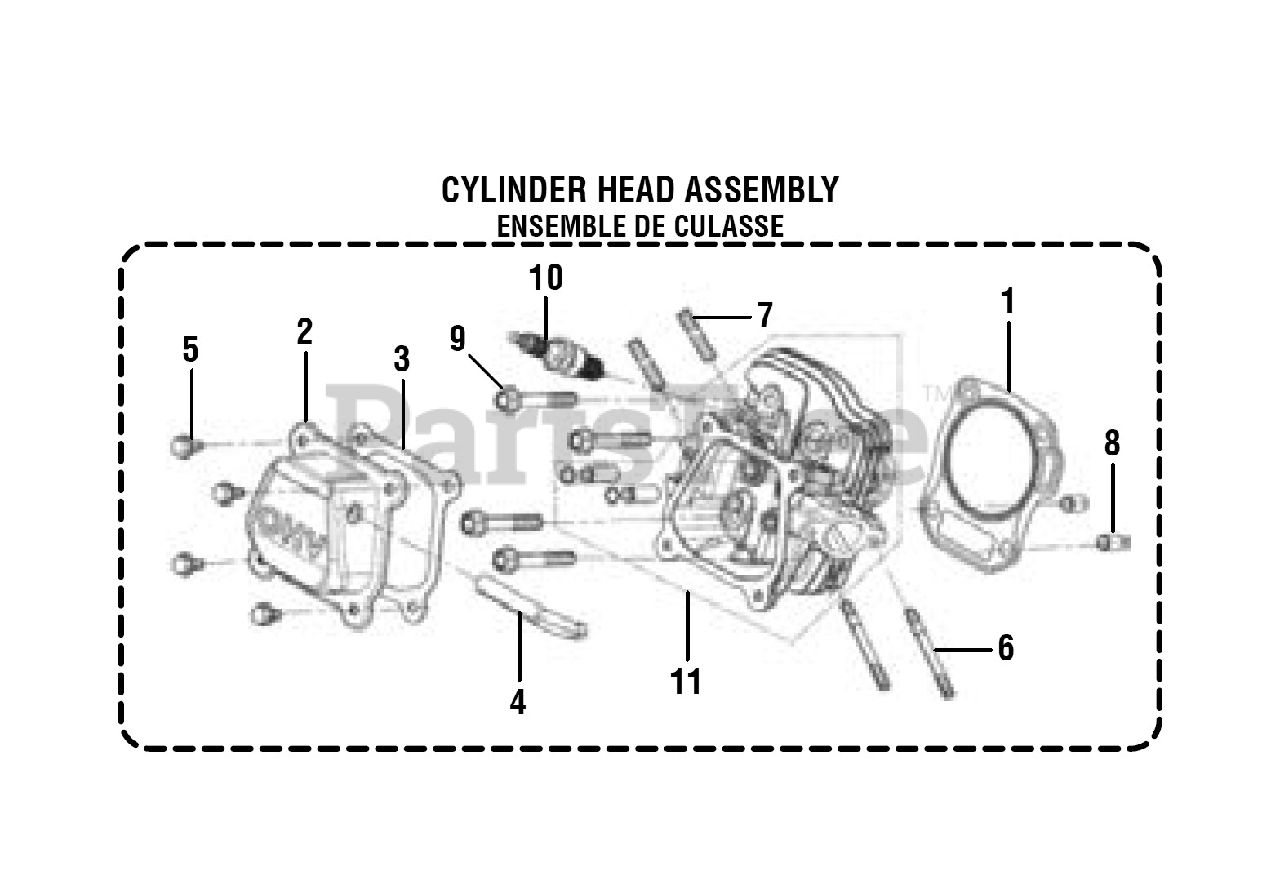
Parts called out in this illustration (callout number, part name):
1	Cylinder Head Gasket
2	Cylinder Head Cover Assembly
3	Cylinder Head Cover Gasket
4	Breather Tube
6	Stud
7	Stud
9	Cylinder Head Bolt
10	Spark Plug
11	Cylinder Head Assembly
